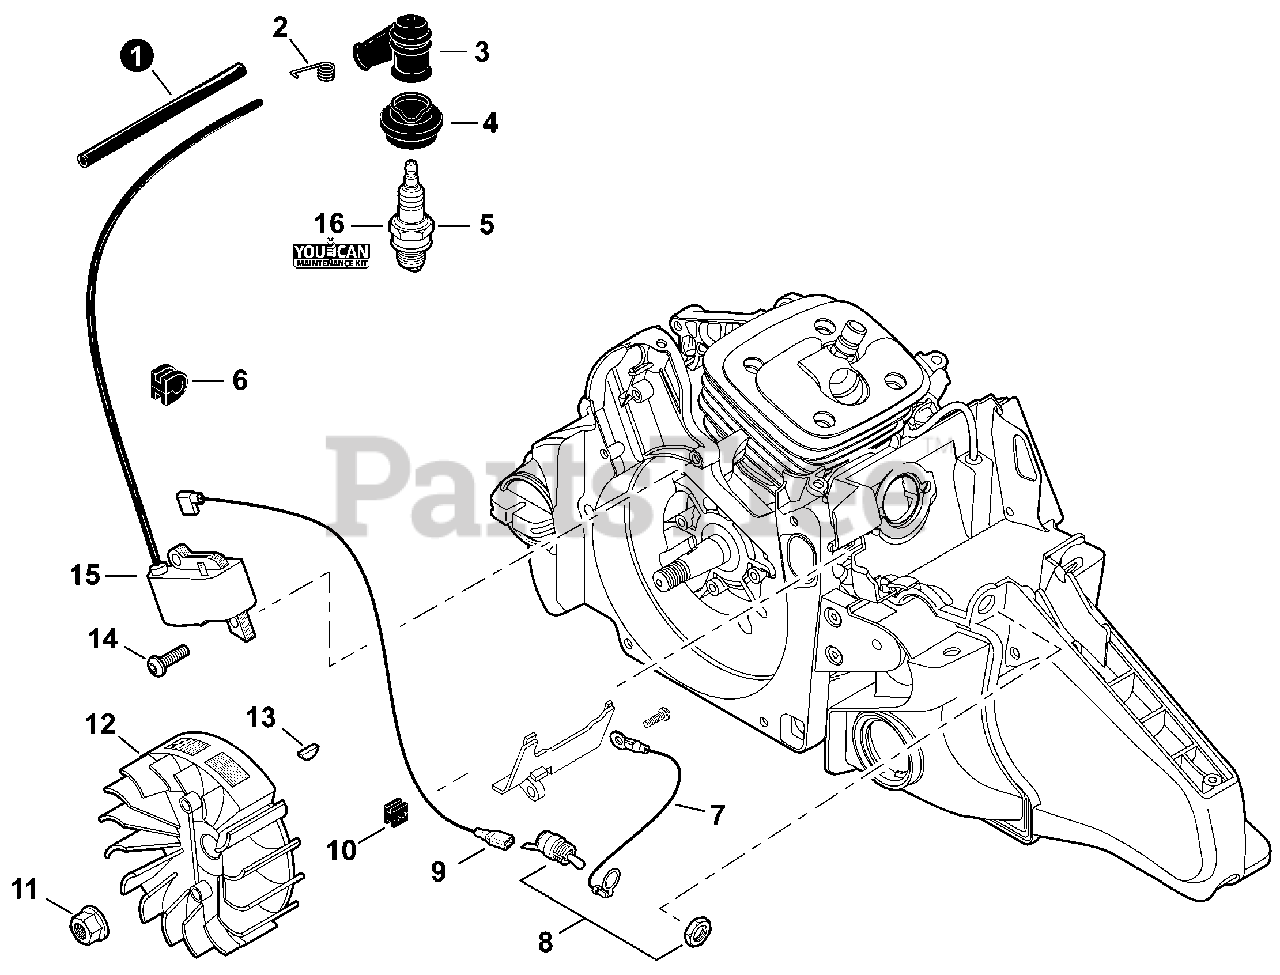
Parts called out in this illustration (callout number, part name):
1	TUBE, IGNITION COIL 6×7.2×70
2	TERMINAL, SPARK PLUG
3	CAP, SPARK PLUG
4	SEAL, SPARK PLUG
5	SPARK PLUG - BPMR8Y
7	LEAD - GROUND L= 170
8	SWITCH, ON-OFF
9	LEAD - IGNITION L= 280
10	GROMMET, LEAD
11	NUT, FLANGE M8
12	FLYWHEEL
13	KEY, WOODRUFF
14	BOLT, TORX 5×16
15	COIL, IGNITION
16	TUNE-UP KIT - YOUCAN™
